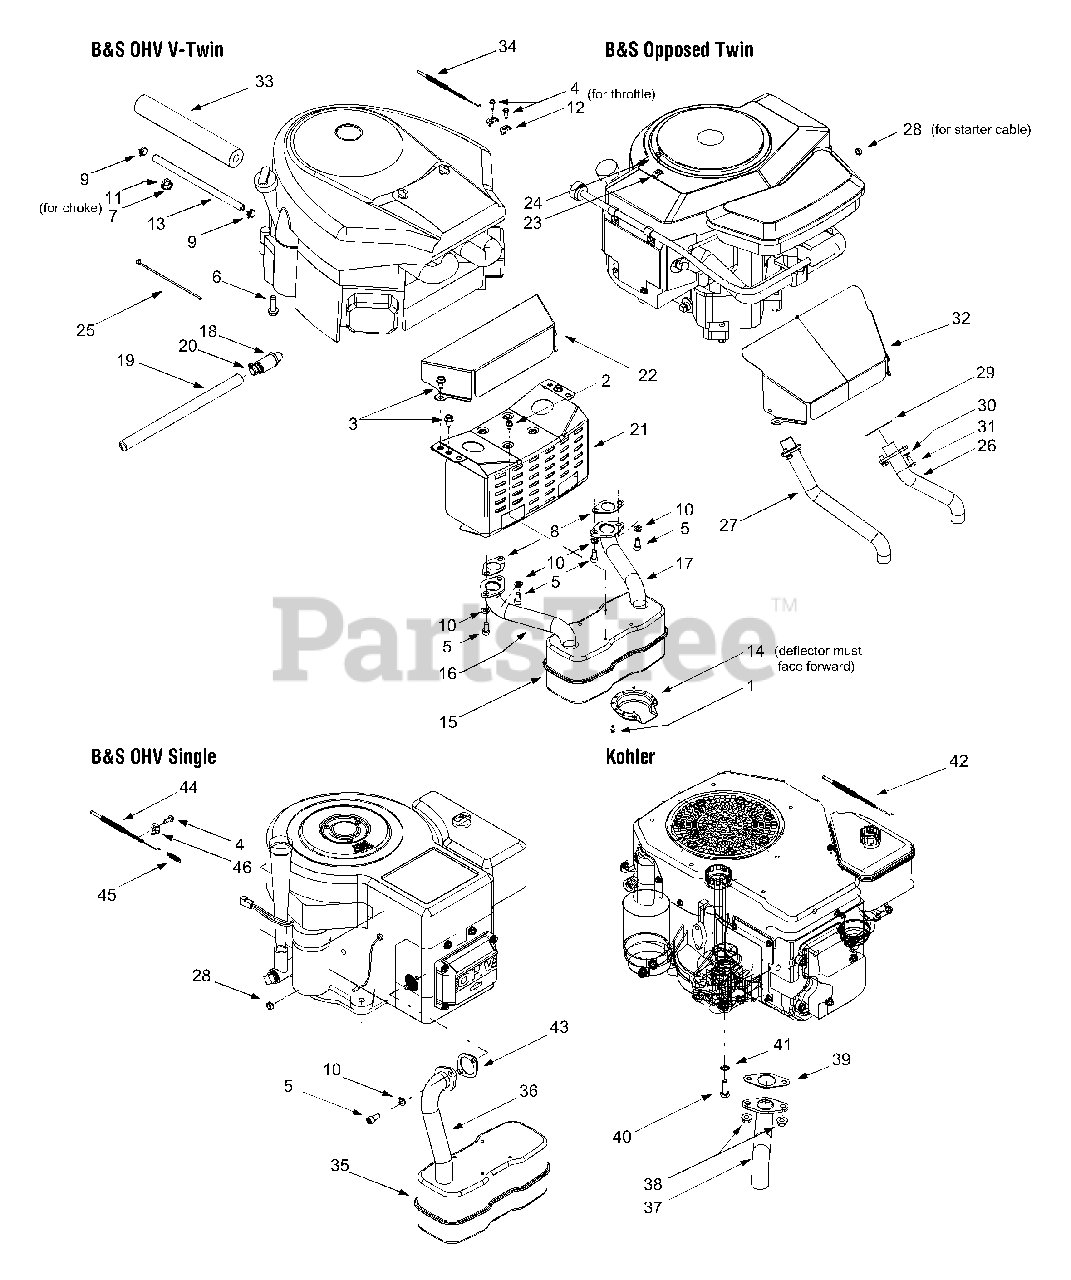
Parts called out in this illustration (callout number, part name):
1	Self-tapping Screw, #8-18 x.50
2	Self-tapping Screw, 1/4-20 x.50
3	Self-tapping Screw, 5/16-18 x.625
4	Screw, #10-32 x.625 (B&S OHV V-Twin)
5	Socket Cap Screw, 5/16-18 x.625
6	Self-tapping Screw, 3/8-16 x 1.25
7	Hex Nut, 3/8-16
8	Exhaust Gasket (B&S OHV V-Twin)
9	Hose Clamp
10	Lock Washer, 5/16
11	Lock Washer,.406 x.875 x.059
12	Casing Clamp (B&S OHV V-Twin)
13	Fuel Line Hose
14	Muffler Deflector
15	Muffler, Twin Inlet (B&S Opposed Twin & OHV V-Twin)
16	RH Exhaust Pipe (B&S OHV V-Twin)
17	LH Exhaust Pipe (B&S OHV V-Twin)
18	Oil Drain Valve
19	Oil Drain Hose
20	Oil Drain Cap
22	Engine Heat Shield (B&S OHV V-Twin)
23	Clamp, 9/16 (B&S Opposed Twin)
24	Screw, #10-16 x.5 (B&S Opposed Twin)
25	Cable Tie
26	LH Exhaust Pipe (B&S Opposed Twin)
27	RH Exhaust Pipe (B&S Opposed Twin)
28	Hex Sems Nut, 1/4-20 (B&S Opposed Twin & OHV Single)
29	Exhaust Gasket (B&S Opposed Twin)
30	Lock Washer, 1/4 (B&S Opposed Twin)
31	Hex Screw, 1/4-20 x.750 (B&S Opposed Twin)
33	Foam,.625 x 1.5 x 10 (fits over fuel line)
34	Throttle Cable (B&S Opposed Twin & OHV V-Twin)
35	Muffler, Single Inlet (B&S OHV Single & Kohler)
36	Exhaust Pipe (B&S OHV Single)
37	Exhaust Pipe (Kohler)
38	Flange Nut, 8mm (Kohler)
39	Exhaust Gasket (Kohler)
40	Hex Cap Screw, 8mm (Kohler)
41	External Lock Washer (Kohler)
42	Throttle Cable (Kohler)
43	Exhaust Gasket (B&S OHV Single)
44	Throttle Cable (B&S OHV Single)
45	Extension Spring,.275 x 1.25 (B&S OHV Single)
46	Casing Clamp (B&S OHV Single)
